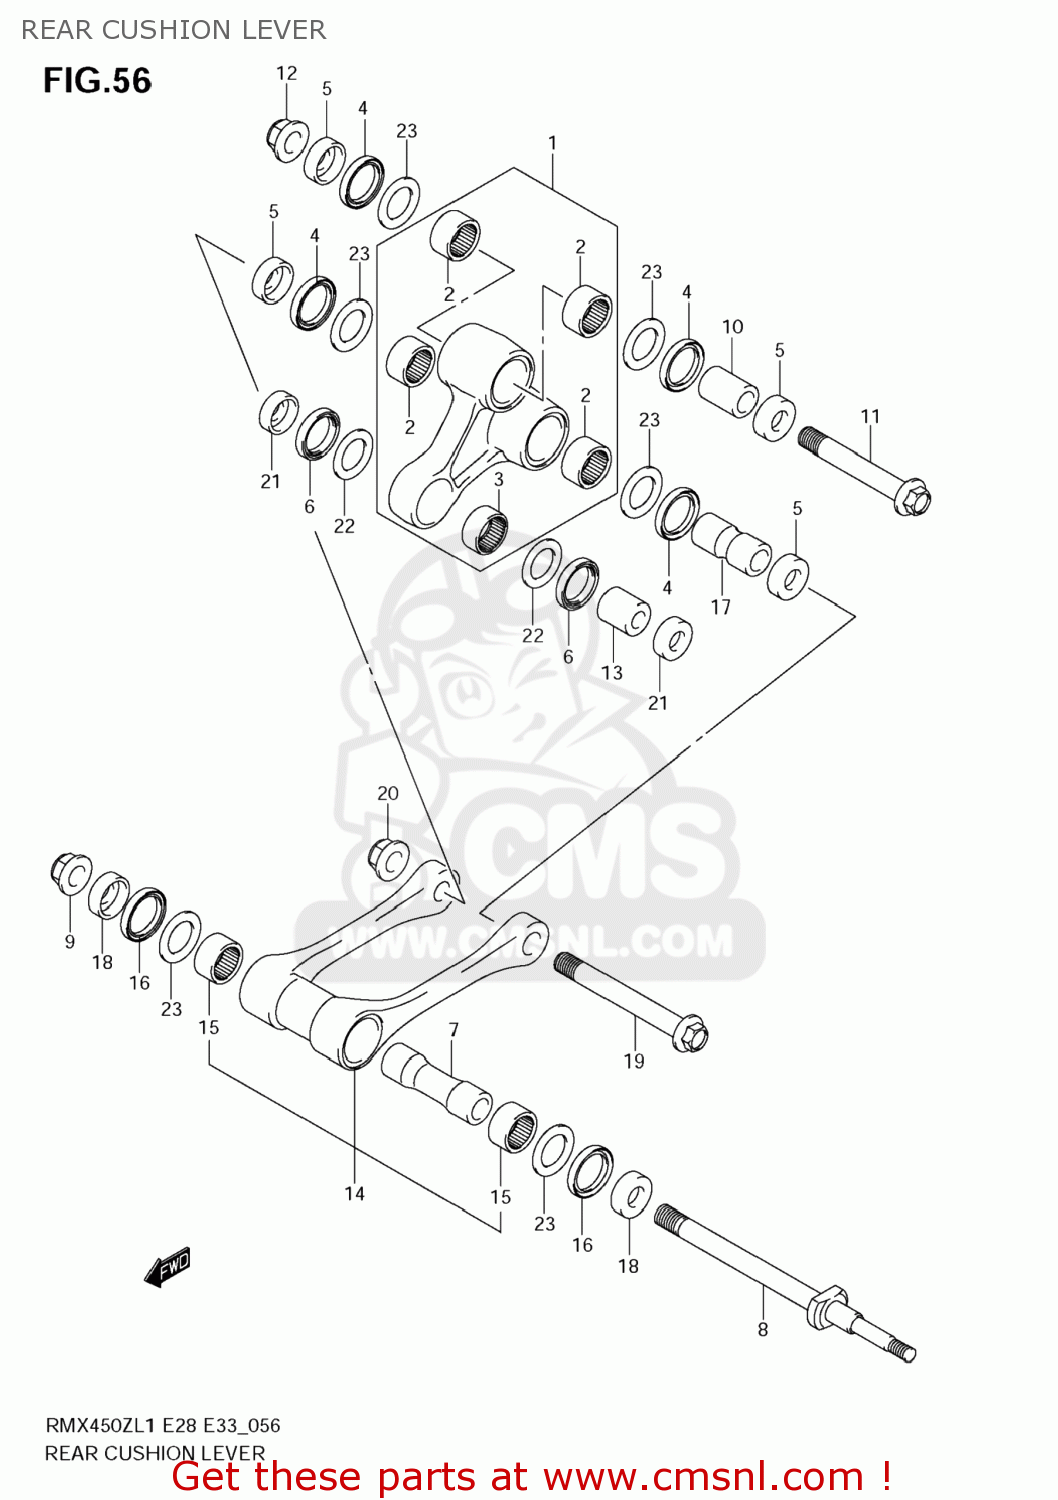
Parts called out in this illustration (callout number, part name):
1	LEVER SET,RR CUSHION
2	BEARING(20X26X14)
3	BEARING(16X22X12)
4	SEAL,OIL(24X31X5)
5	SPACER,RR CUSHION LEVER SIDE
6	SEAL,OIL(22X28X4)
7	SPACER,RR CUSHION ROD
8	BOLT,RR CUSHION ROD
9	NUT
10	SPACER,RR CUSHION LEVER UPR
11	BOLT,RR CUSHION LEVER UPR
12	NUT
13	SPACER,RR CUSHION LEVER FR
14	ROD SET,RR CUSHION
15	BEARING(20X26X14)
16	SEAL,OIL(24X31X5)
17	SPACER,RR CUSHION LEVER LWR
18	SPACER,RR CUSHION LEVER SIDE
19	BOLT,RR CUSHION LEVER LWR
20	NUT
21	SPACER,RR CUSHION LVR FR SIDE
22	SHIM(16X28X0.5)
23	WASHER
